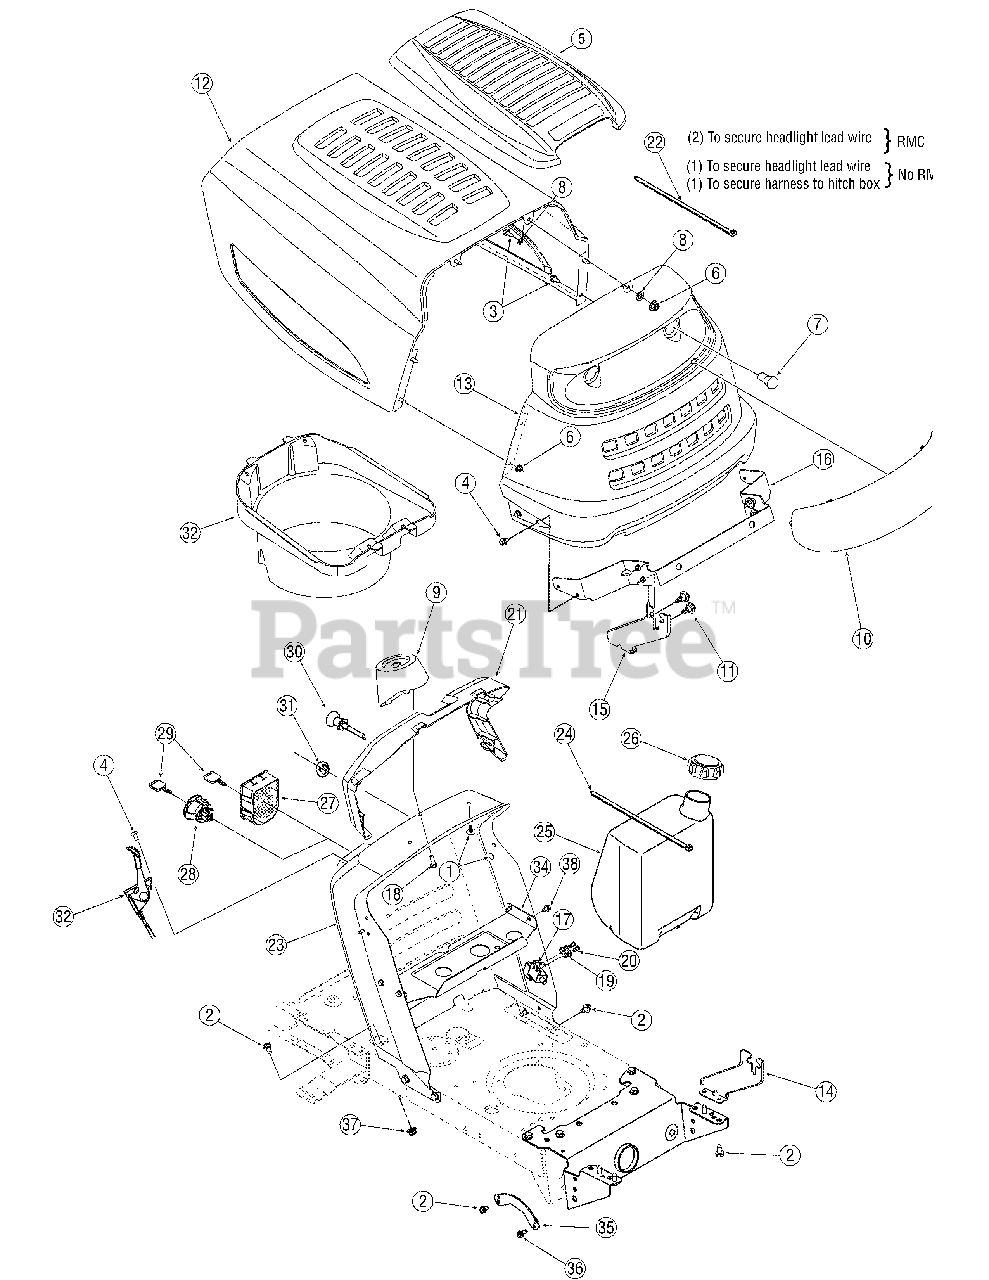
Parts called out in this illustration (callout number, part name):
1	Ratchet Clip .250 Dia. x .500 Lg.
2	Screw, 5/16-18, 0.625
3	Screw, 1/4-20, .620, Gr5
4	Screw, 1/4-20, .500
5	5-Style Hood Cover
6	Nut, Flange Lock, 1/4-20, Gr5
7	Headlamp, 12V
8	Washer, Flat, .265 x .938 x .120
9	Support, Steering
10	Lens
11	Screw, Shoulder, .43 x.29, 5/16-18
18	Screw, 1/4-15, 0.750
19	Switch Plate
20	Pop Rivet
24	Cable Tie, 34.75
25	Fuel Tank, 1.5 gal.
26	Fuel Tank Cap
27	Module, Ignition Switch (RMC)
28	Igntion, Switch (No RMC)
29	Key
30	Choke Control, 37.5"
32	Plenum (Single Cylinder Engine)
32	Plenum (Kohler Single Cylinder)
32	Plenum (Twin Cylinder Engine)
33	Throttle/Choke Control, 25" (Single Cylinder Engine)
33	Throttle Control, 39" (Twin Cylinder Engine)
36	Screw, 5/16-18 x .750
37	Flange Lock Nut 5/16-18
38	Screw, 1/4-20, 0.500
